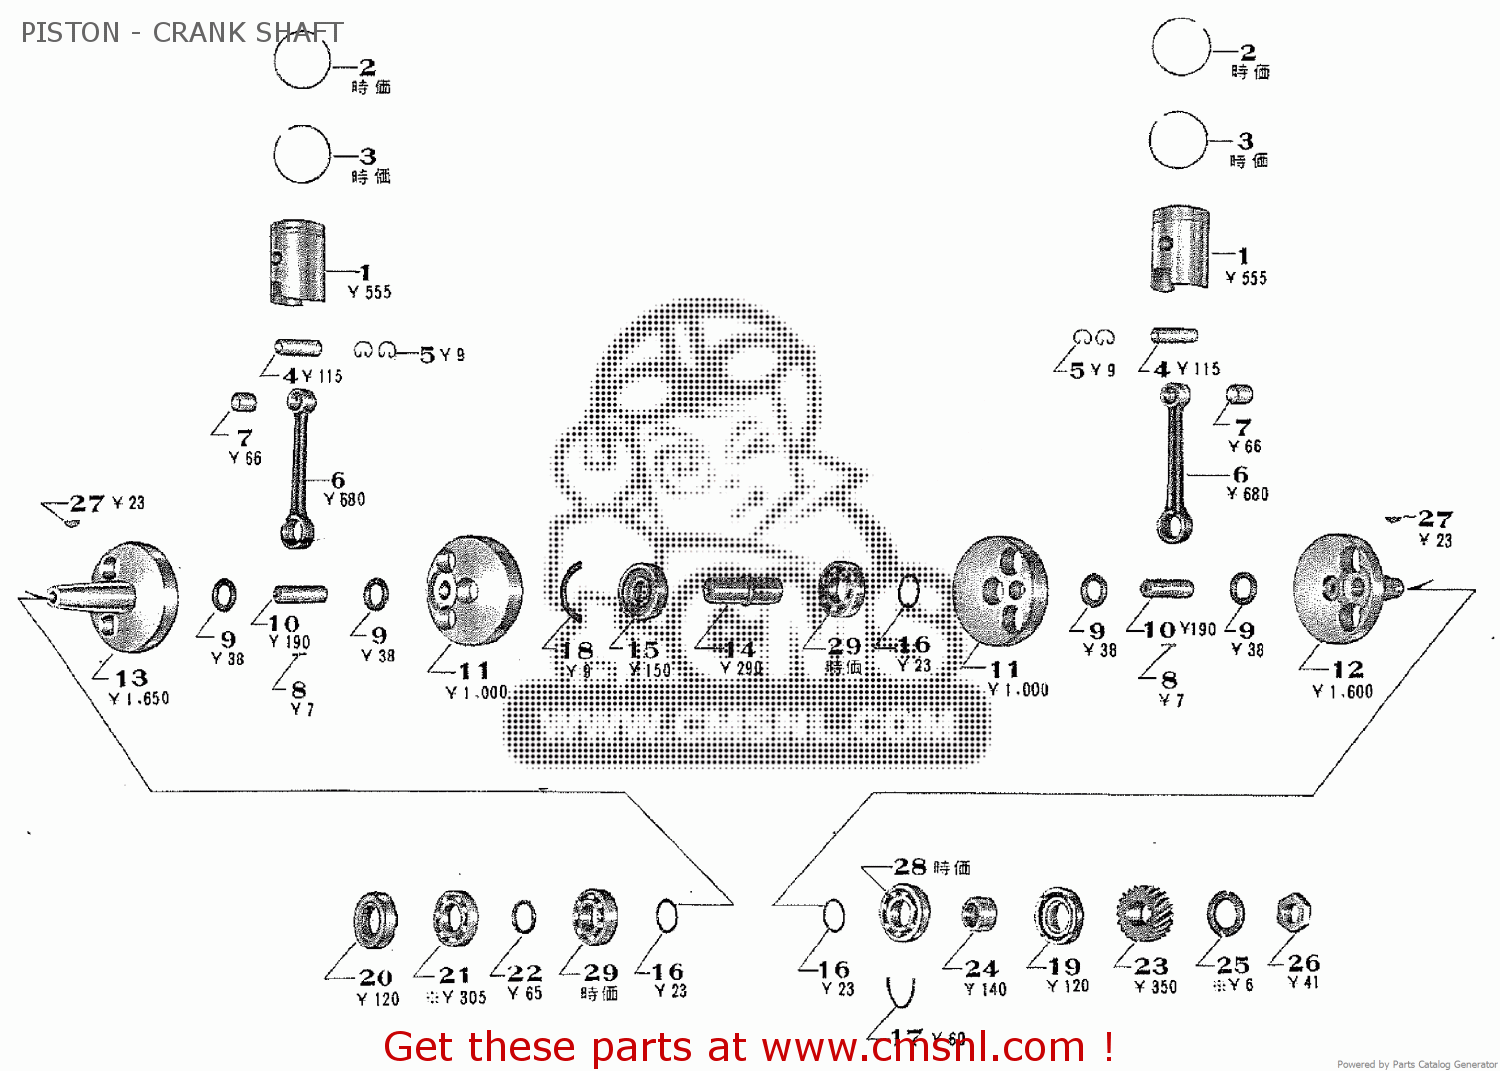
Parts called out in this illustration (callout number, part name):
1	PISTON
2	PISTON RING (TOP)
3	PISTON RING (SECOND)
4	PISTON PIN
5	CRANK SHAFT ASSY.
6	CONNECTING ROD COMP
7	CONNECTING ROD SMALL END BUSH
8	CONNECTING ROD NEEDLE ROLLER
9	CONNECTING ROD THRUST WASHER
10	CRANK PIN
11	CRANK WHEEL
12	RIGHT CRANK SHAFT
13	LEFT CRANK SHAFT
14	MIDDLE CRANK SHAFT
15	MIDDLE CRANK SHAFT OIL SEAL
16	CRANK SHAFT THRUST WASHER
17	BEARING KNOCK RING
18	MIDDLE CRANK SHAFT OIL SEAL CIRCLIP
19	RIGHT CRANK SHAFT OIL SEAL
20	LEFT CRANK SHAFT OIL SEAL
21	LEFT CRANK SHAFT OUTER BEARING
22	BEARING DISTANCE COLLAR
23	PRIMARY PINION
24	PRIMARY PINION DISTANCE COLLAR
25	PRIMARY PINION SET WASHER
26	PRIMARY PINION SET NUT
27	4MM WOODRUFF KEY
28	BEARING
29	BEARING
